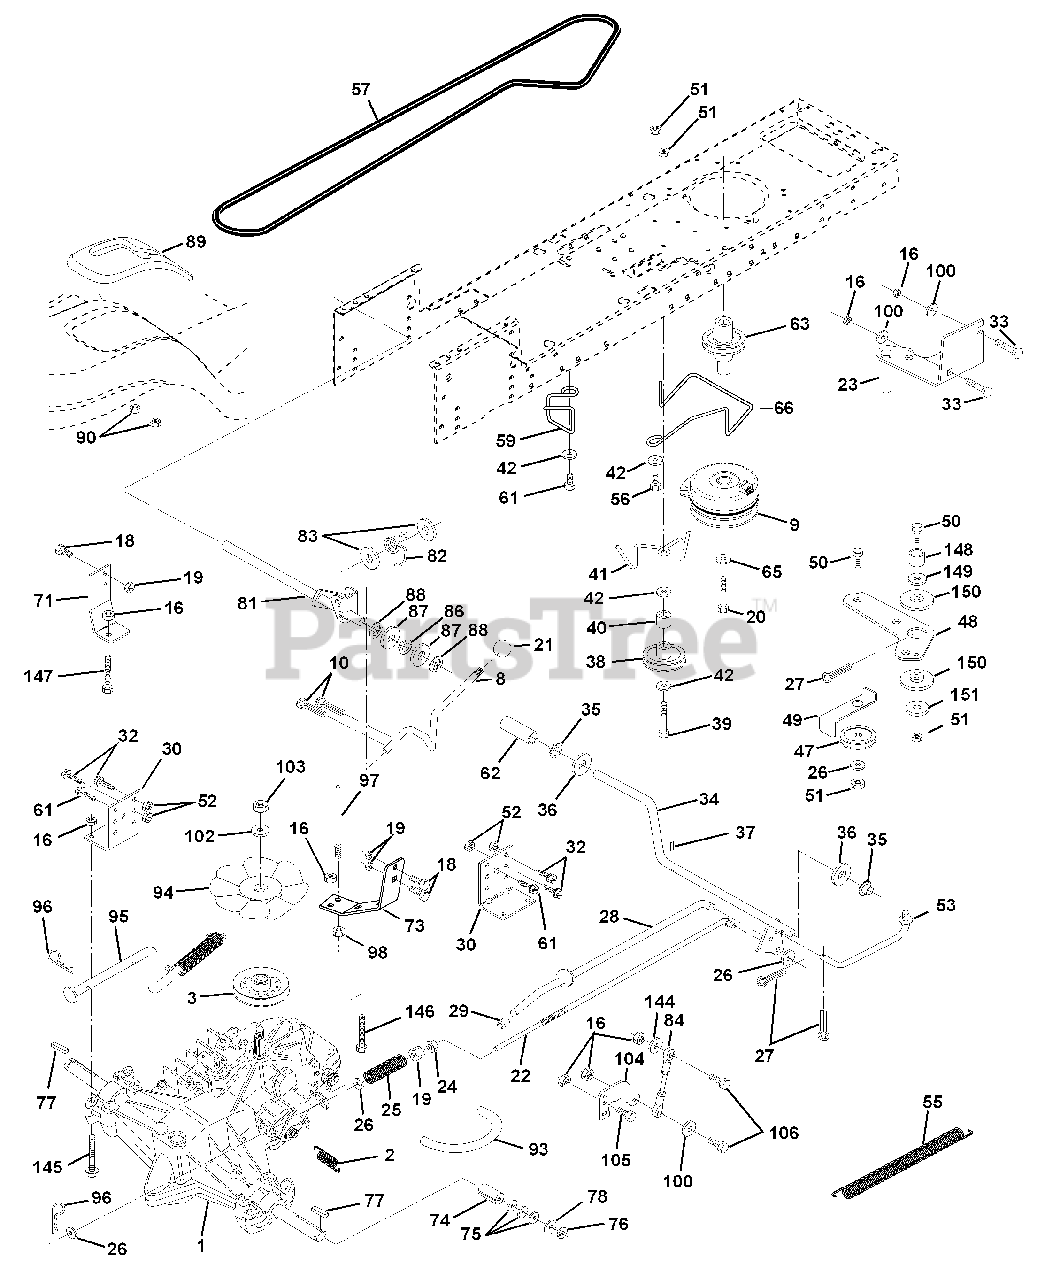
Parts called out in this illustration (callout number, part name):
1	Transaxle w/cas Hydro 319-0650
2	Spring, Return, Brake
3	Pulley, Transaxle Hydro 750 LT
8	Rod Shift STLT
9	Clutch Elecric
10	Pin Cotter 1/8 x 1 CAD
15	Bolt Hex 5/16-18 Unc Flghd
16	Nut Lock Hex W/Ins. 5/16-18 Unc P
18	Bolt Fin Hex 3/8-16 Unc x 1 Gr.5
19	Nut Lock Hex W/Ins 3/8-16 Unc
20	Bolt, Hex 7/16-20 x 4-1/4 Ga. 5
21	Knob Deluxe 1/2-13 UNC BLK/BLK
22	Rod, Brake Hydro
23	Bracket Asm Mtg CL
24	Nut Hex Jam 3/8-16 UNC
25	Spring, Brake Rod
26	Washer
27	Pin Cotter 1/8 x 3/4 CAD.
28	Rod, Parking Brake
29	Cap,Parking Brake
30	Bracket, Transaxle
32	Bolt Hex Hd 5/16-18 Unc x 3/4
33	Bolt Carriage 5/16-18 UNC x 3/4
34	Shaft, Foot Pedal
35	Bearing, Nylon
37	Pin, Roll
38	Pulley, Idler, Flat
40	Spacer Split
41	Keeper, Belt Idler
42	Washer 13/32 x 13/16 x 12 Ga
47	Pulley, Idler, V-Groove Plastic
48	Bellcrank Clutch Grnd Drv STL
49	Retainer, Belt Style Spring
50	Bolt
52	Nut Crown Lock 5/16-18
53	Link, Clutch
55	Spring, Return, Clutch
56	Bolt, Fin Hex 3/8-16 UNC x 1 1/4
57	V-Belt, Ground Drive
59	Keeper, Center Span
61	Screw Thdrol. 3/8-16 x 3/4 Ty. TT
62	Cover, Pedal Premium
63	Pulley, Engine
65	Washer Lock Hvy HLCL Spr 7/16
66	Keeper Belt Engine
71	Strap Torque Lh Hydro 18/20" T
73	Strap Torque Rh Hydro 0650
74	Spacer, Split
75	Washer 25/32 x 1-1/4 x 16 Ga.
77	Key, Square
78	Washer 25/32 x 1-5/8 x 16 Ga
81	Shaft Asm. Cross Hydro 20" Tires
82	Spring Torsion T/A
83	Washer 17/32 x 3/4 x 16 Ga.
84	Rod, Tie Hydro 20" Tires
87	Washer 21/32 x 1-1/4 x 16 Ga.
88	Ring Klip #5304-62
89	Console, Shift Hydro STLT
90	Nut Self-Thd Wsh-Hd 1/4 Zinc
93	Line Fuel Hydro 4"
94	Fan, Hydro 7"
95	Control Asm. Bypass Hydro
96	Retainer Spring 1" Zinc/Cad
97	Keeper Belt Rh Hydro 0750.18/20"
98	Nut Keps Hex 3/8-16 Unc
100	Washer 11/32 x 3/4 x 16 Ga.
102	Washer Belleville .501D x 1.50D
103	Nut Hex Jam Toplock 1/4-20 Unf
104	Arm, Control Hydro
105	Screw Cap Hex 5/16 x 18 x 1
106	Bolt Fin Hex 5/16-18 Unc x 1-1/4
144	Washer 11/32 x 5/8 x 16 Ga.
145	Bolt Hex Flghd 5/16-18 x Gr. 5
146	Bolt Hex Flghd 5/16-18 x 2-1/4
147	Bolt Hex Flghd 5/16-18 x 1-1/2
149	Spacer Retainer PM Mower
150	Bushinf Nylon Collered
151	Washer 13/32 x 2 x 10 Ga.
